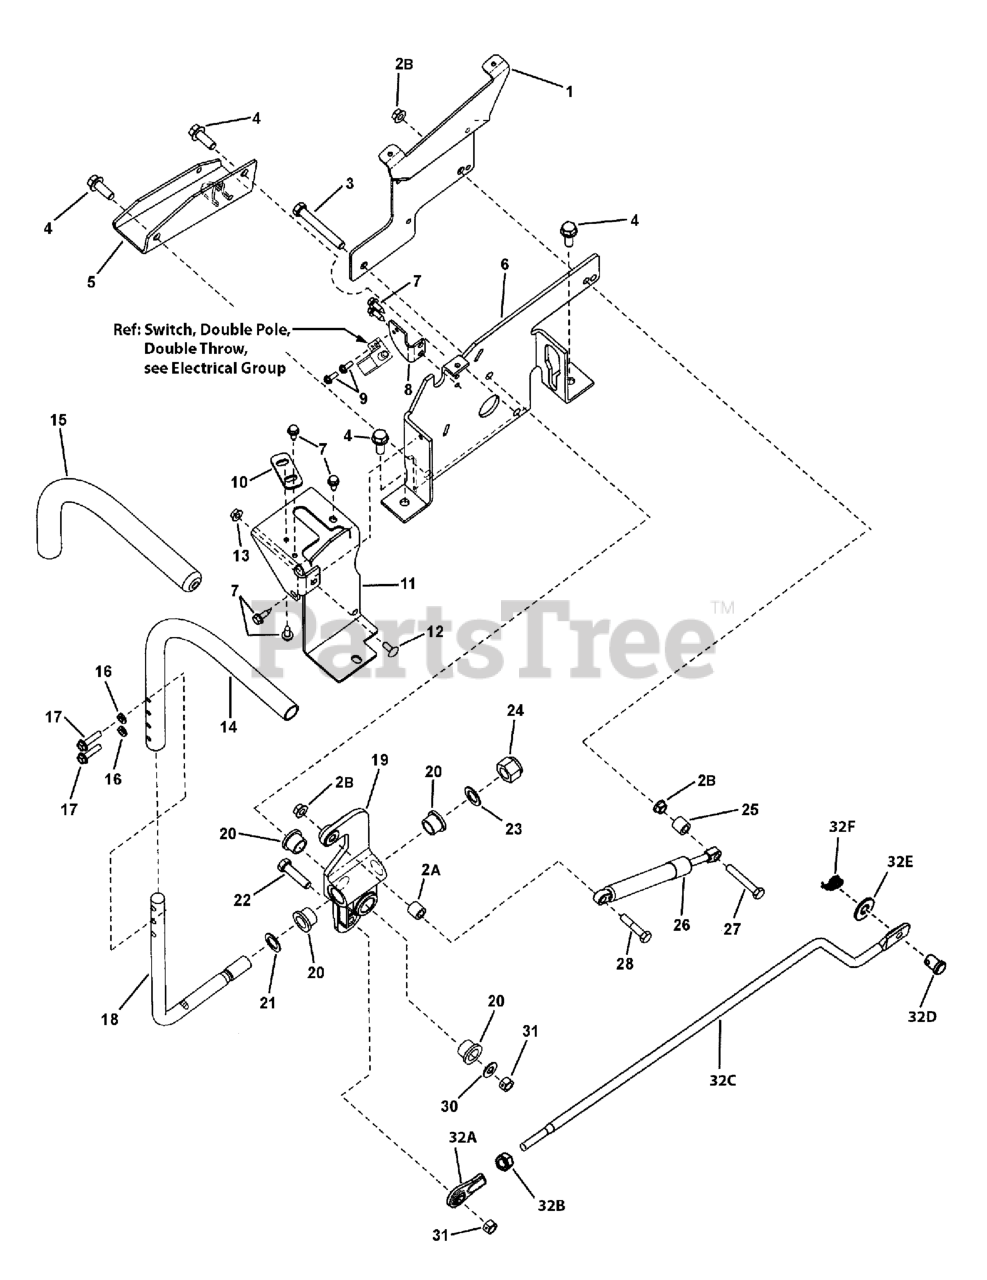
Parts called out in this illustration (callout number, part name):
1	BRACKET, Fender Support, RH
2A	SPACER, 9/16 OD
2B	NUT, 1/4-20 Hex Center Lock
3	BOLT, Shoulder, 3/8-16
4	SCREW, 3/8-16 x 1" Hex Washer Self-Tap
5	BRACKET, Mount, Motor
6	CONTROL BRACKET, RH
7	SCREW, 1/4-20 x 3/4" Hex Washer Self-Tap, Black
8	BRACKET, Switch
9	SCREW, #10-24 x 1/2" Hex Washer Self-Tap, Torx
10	PLATE, Foward/Reverse Adjust
11	BRACKET, Guide, Stick, Control, RH
12	BOLT, 1/4-20 x 5/8" Round Head Short Square Neck, GR 5, YZ
13	NUT, 1/4-20 Hex Flange Lock, Black
15	GRIP, Handle
16	LOCKWASHER, 1/4" Spring, YZ
17	SCREW, 1/4-20 x 1" Hex Head Cap, GR 5, BZ
18	ROD, Handle, RH
19	CONTROL BRACKET ASSEMBLY
20	BEARING, Flange
21	WASHER, .64 x .99 x .05 Flat, YZ
22	SCREW, 3/8-16 x 1-1/2 Hex Head Cap, GR 5, YZ
23	WASHER, 5/8 ID x 1.00 OD x .065 Nylon
24	NUT, 5/8-18 Hex Nyloc, YZ
26	DAMPENER, Control
27	SCREW, 5/16-18 x 2" Hex Head Cap, GR 5, YZ
28	BOLT, Shoulder, 5/16 x 1/4-20
30	WASHER, Thrust
31	NUT, 3/8-16 Hex Center Lock, YZ
32A	ROD END, (3/8-24 thread)
32B	NUT, 3/8-24 Hex, GR B, YZ
32C	ROD, Link Foward/Reverse (3/8-24 thread)
32D	PIN, 7/16 x 1" Clevis
32E	WASHER, 3/8" Flat
32F	COTTER PIN, 1/2 Self, YZ
